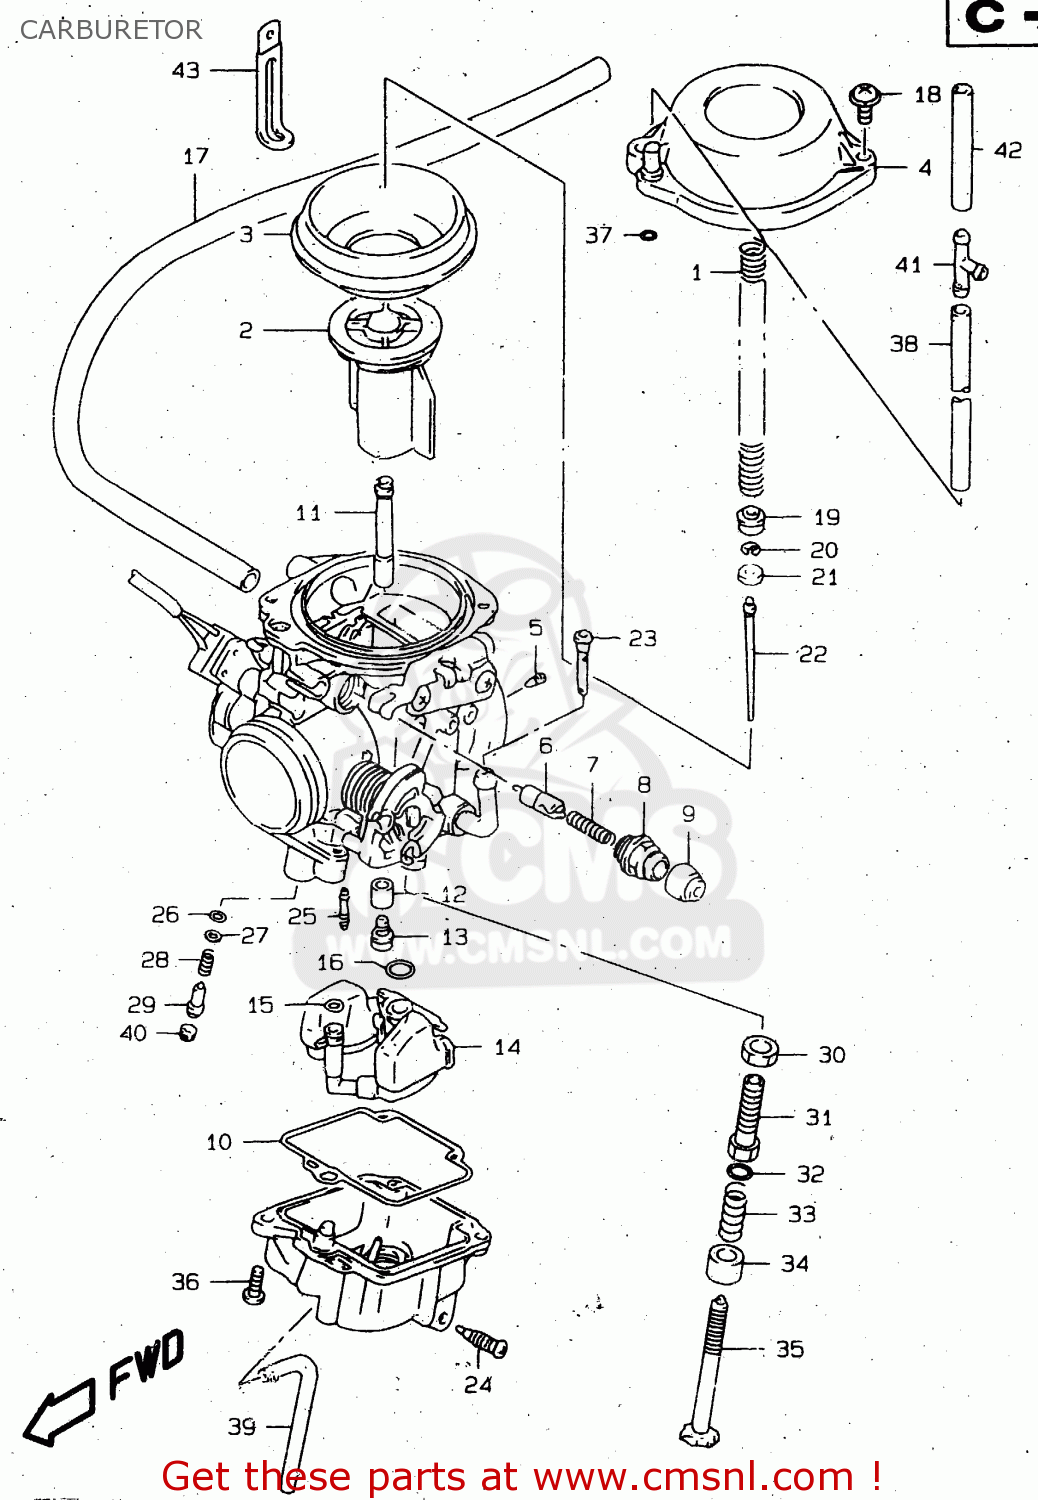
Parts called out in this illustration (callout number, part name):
1	SPRING
2	VALVE,PISTON
3	DIAPHRAGM
4	COVER,DIAPHRAGM
5	JET,AIR(1.0)
6	PLUNGER
7	SPRING
8	HOLDER,GUIDE
9	CAP
10	GASKET,FLOAT CHAMBER (NAS)
11	JET,NEEDLE(Y-5M)
12	RING
13	JET,MAIN(140)
14	FLOAT/NEEDLE VALVE ASSY
15	O RING
16	O-RING,NEEDLE VALVE
17	HOSE(6.5X10.5X275)
18	SCREW
19	RING
20	CLIP,NEEDLE
21	RING
22	NEEDLE,JET
23	FILTER
24	SCREW,DRAIN
25	JET,PILOT(42.5)
26	O RING,PILOT AIR SCREW
27	WASHER
28	SPRING
29	SCREW,PILOT
30	NUT
31	ADJUSTER
32	WASHER,STARTER SHAFT
33	SPRING
34	RING
35	ADJUSTER
36	SCREW(5X14)
37	O RING
38	HOSE(4.5X8.5X600)
39	HOSE(3X5X450)
40	PLUG
41	JOINT,3 WAY
42	HOSE(4.5X8.5X600)
43	CLAMP(L:65)
